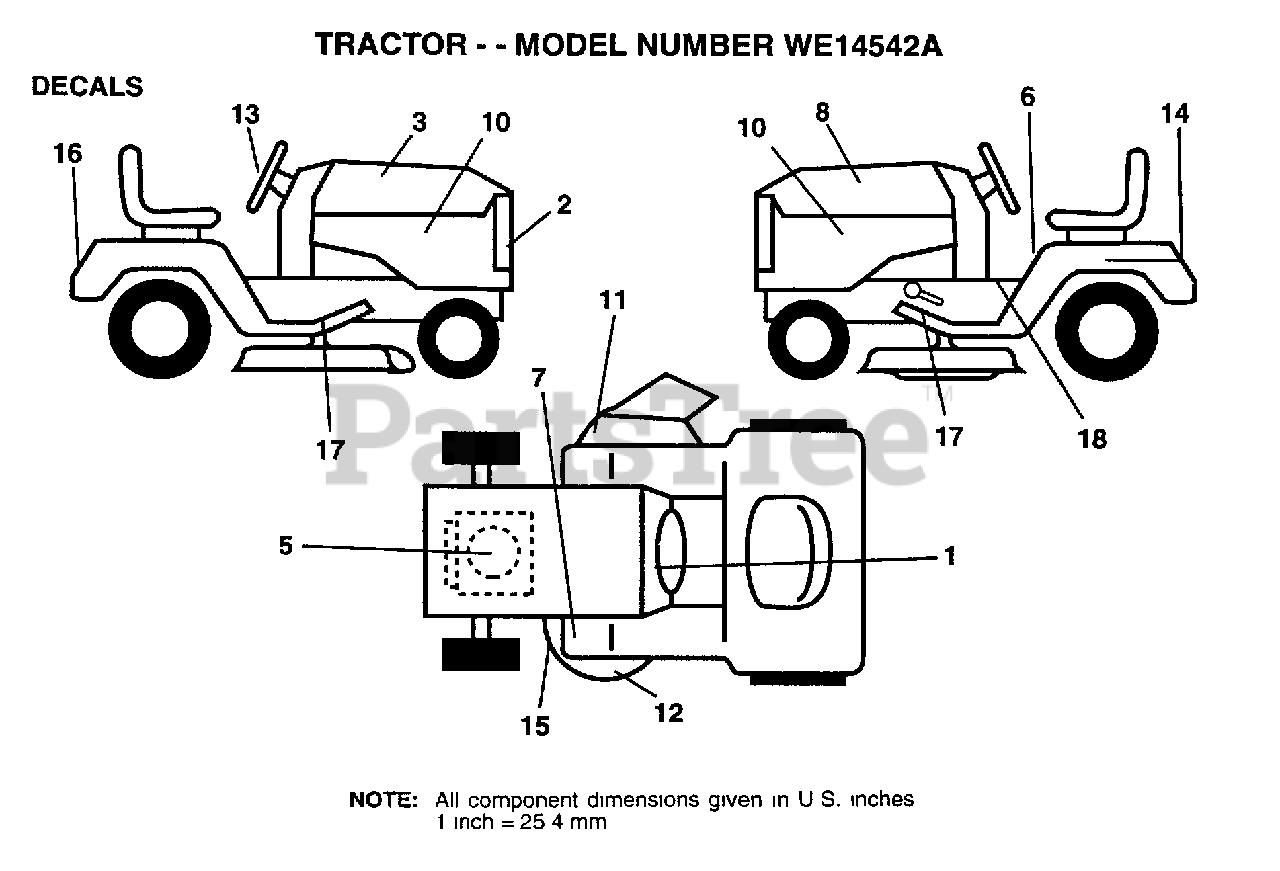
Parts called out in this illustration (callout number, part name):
2	DECAL.GRILL
3	DECAL.HD.RH.WEED
5	DECAL, ENGINE
6	DECAL CAUTION
7	DECAL T
8	DECAL.HD.LH.WEED
10	DCL.PNL.SIDE.
11	"DECAL, WARNING"
12	DECAL.MOWER
13	DECAL.WHL.STRG.
14	DECAL
15	DECAL
16	DECAL.FENDER
17	"PAD,FOOTREST"
18	DECAL BRAK PARK
